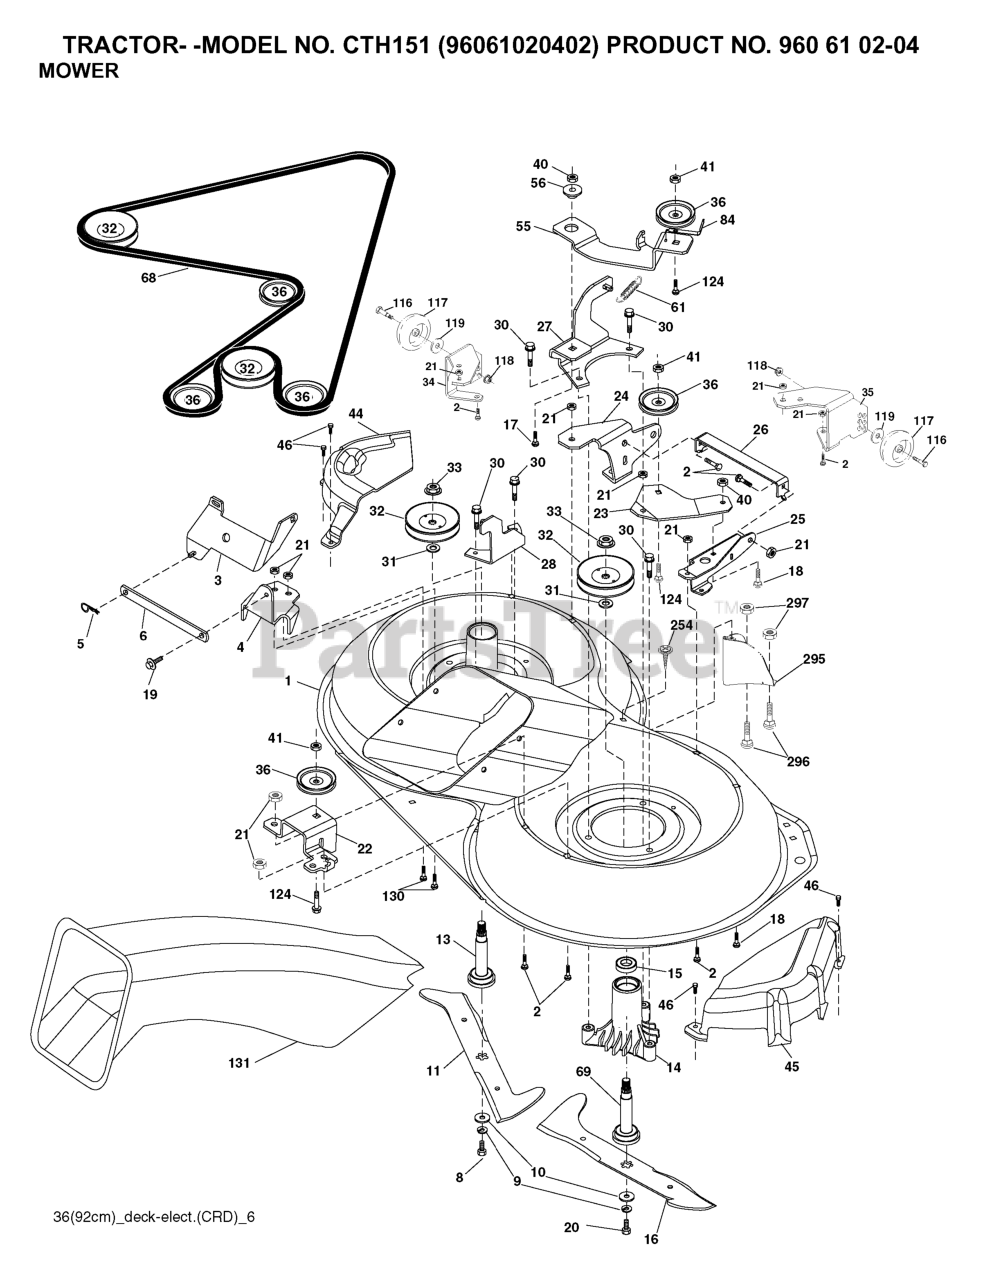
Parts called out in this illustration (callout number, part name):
2	RP BOLT 5/16-18 X3/4 ZN/YEL GR
5	RETAINER-SPRNG RB
6	BAR.SWAY.92.CRD
8	BOLT.3/8-24X1.25 GR8
9	LOCKWASHER
10	WASHER.BLADE
13	SHAFT ASM VENT
14	HOUSING.MANDREL.VENTED (MACHD)
17	BOLT.3/8-14X1.25
19	BOLT SHD 5/16-18
20	BOLT.3/8-24X1.25GR8. LHTHRD
21	LOCKNUT
26	SUPPORT
30	SCREW, WASHER HEAD
31	WASHER.SPACER.MANDREL
32	PULLEY MANDREL
33	NUT.FLANGE.LOCK.TOP
36	PULLEY.IDLER.4.25
41	NUT LOCK FLG 3/8-16 UNC
45	COVER.MANDREL.RH.CRD
46	SCREW.1/4-20X5/8
55	ARM.IDLER.92 CRD.2006
56	SPACER.RETAINER.MOWER
61	SPRING
68	BELT.DRIVE.92CM.CRD.2006
69	SHAFT.ASM.W/LWR.BRG.RH.THREAD
84	KEEPER, BELT IDLER
116	BOLT.SHOULDER.3/8-16X3-5/8.
117	RP WHEEL. GUAGE RALLY
118	NUT LOCK FLG 3/8-16 UNC
119	WASHER
124	BOLT.3/8-16X1.50
130	BOLT.CARR.SQNK.5/16-18UNC.X3/4
131	CHUTE BAGGER
254	SCREW 3/8-16X1
296	BOLT
297	NUT CENTERLOCK
